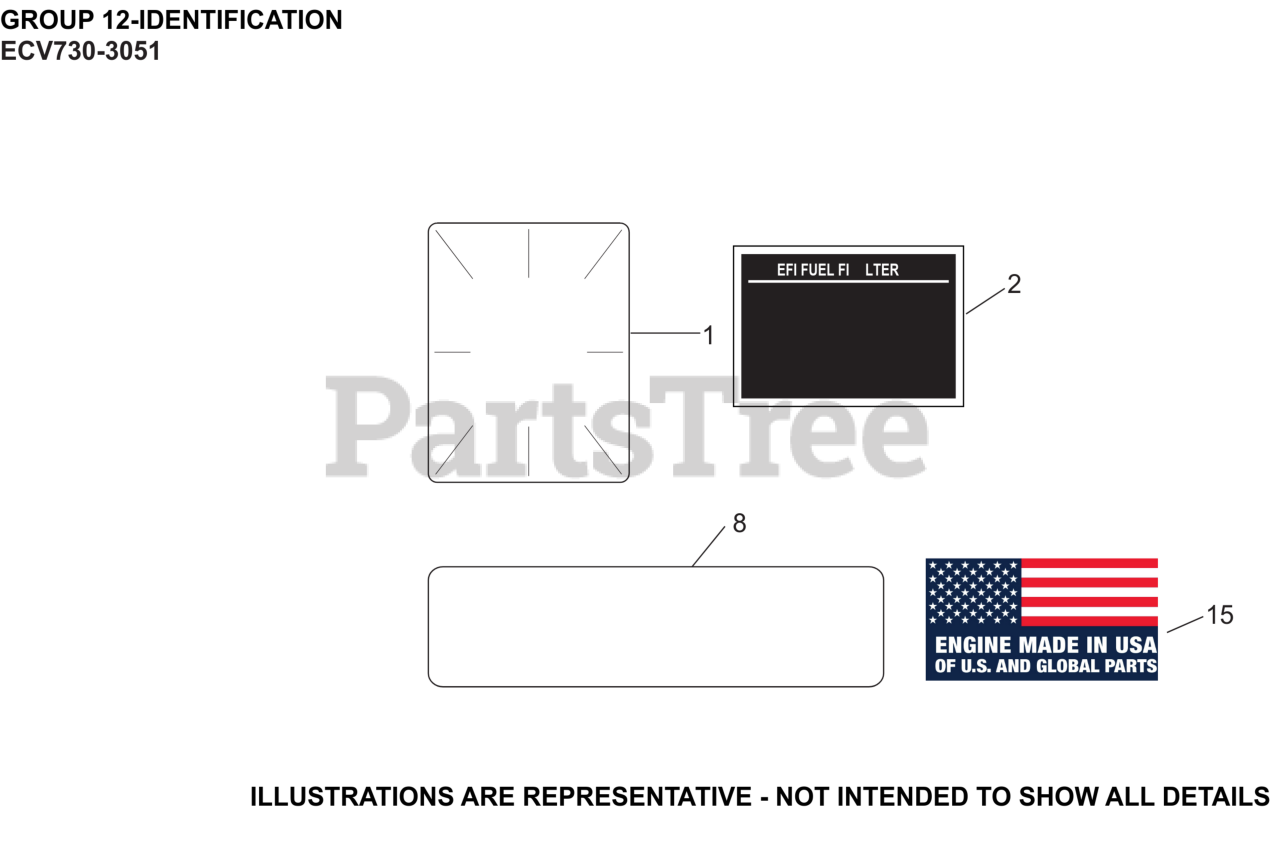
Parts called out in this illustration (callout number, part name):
1	LABEL, CLEAR LAMINATION
2	LABEL, EFI FUEL FILTER
8	DECAL LPAC EMK, ECV730/747cc
15	DECAL, USA
